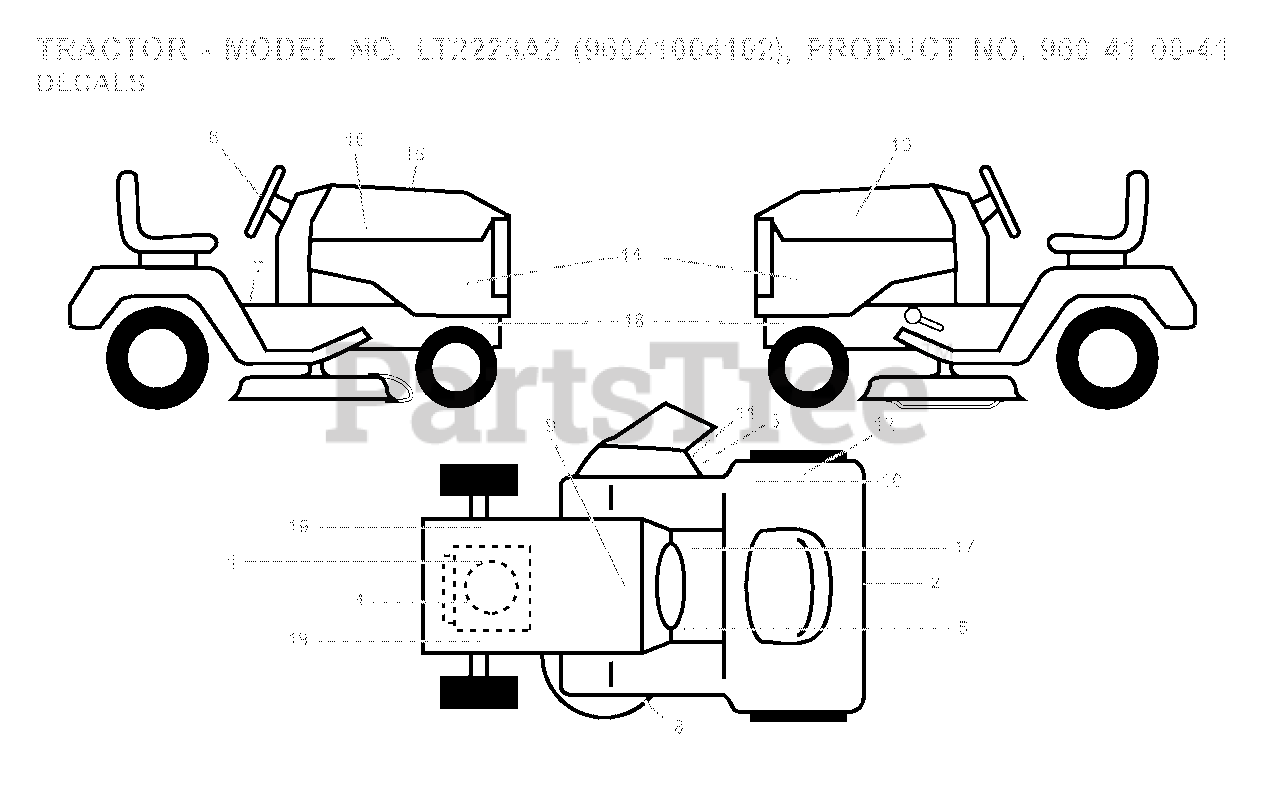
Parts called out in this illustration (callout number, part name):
3	DECAL, DEFLECT WARNING
8	DECAL.MOWER.SCH.48/54
9	DECAL BTRY SYMBOLS
10	DECAL.FENDER
11	DECAL.INTERNATIONL.CUTFINGER
17	DECAL PARK BRAKE
